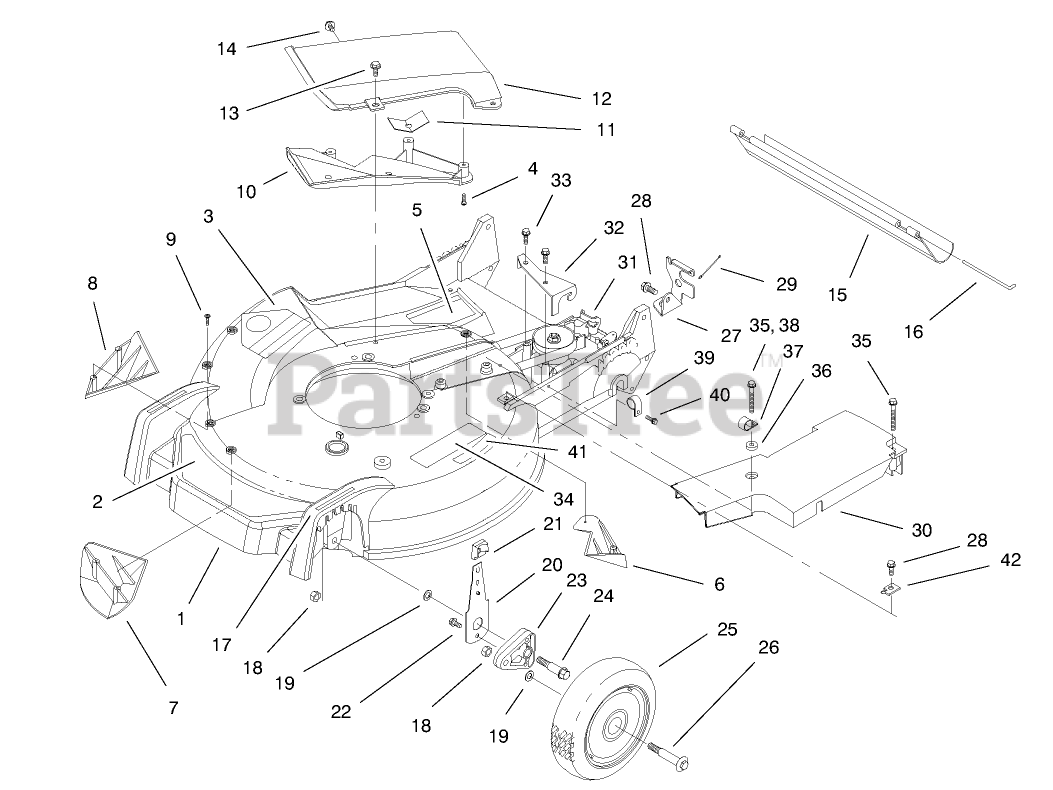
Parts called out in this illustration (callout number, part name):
2	DECAL - DECK
3	DECAL-DANGER
4	Screw-PPH
5	DECAL - DANGER
6	KICKER-REAR
7	KICKER-FRONT
8	KICKER-RH
9	SCREW-PPH
10	Deflector-Recycler
11	Guard-Cover
13	SCREW-HWH
14	SCREW AND WASHER ASM
16	ROD-SHIELD
18	NUT-LOCK
19	WASHER
20	FRONT SPRING ARM ASM
21	KNOB-ARM
22	SCREW-HWH
23	ARM-PIVOT, FRONT
24	BOLT-SHOULDER
25	WHEEL AND TIRE ASM
28	SCREW-HWHTF
29	RETAINER-CABLE
31	GEARCASE ASM
33	SCREW-HWHTF
35	SCREW-HWH
36	WASHER
37	CLAMP-CABLE
38	SCREW-SPECIAL
39	CLAMP-CABLE
40	SCREW-HWH
41	STEP PAD DECAL
42	CLAMP-CABLE
